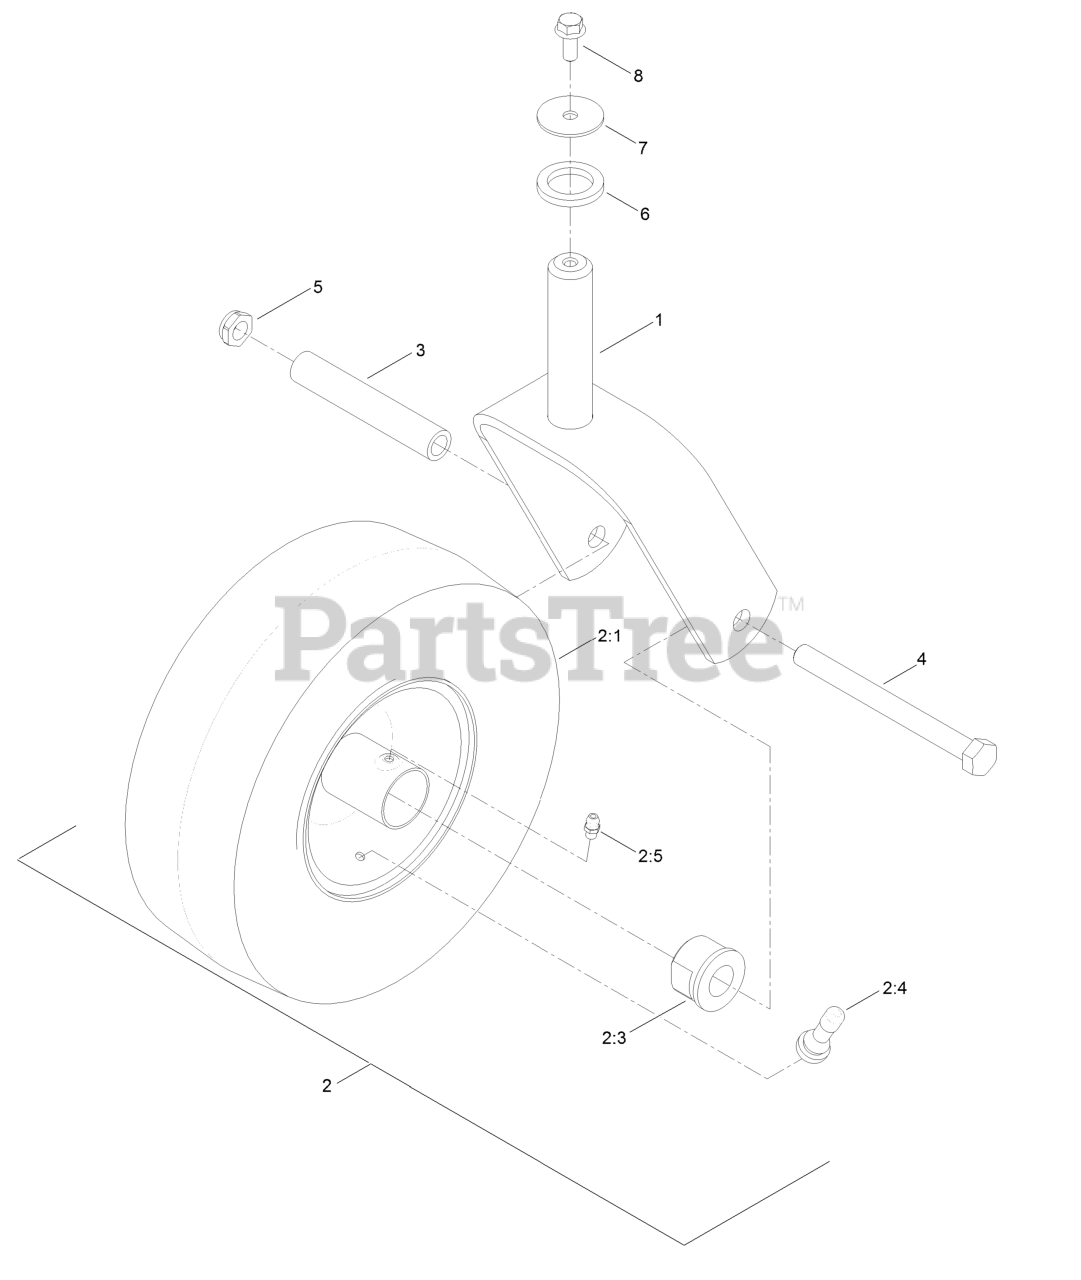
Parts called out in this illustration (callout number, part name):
1	CASTER FORK ASM
2	CASTER WHEEL ASM
2:3	BUSHING-FLANGE
2:4	Stem-Valve
2:5	FITTING-GREASE
3	BUSHING-SPANNER
4	SCREW-HH
5	NUT-HEX
6	WASHER-THRUST
7	WASHER-FLAT
8	SCREW-HHF
